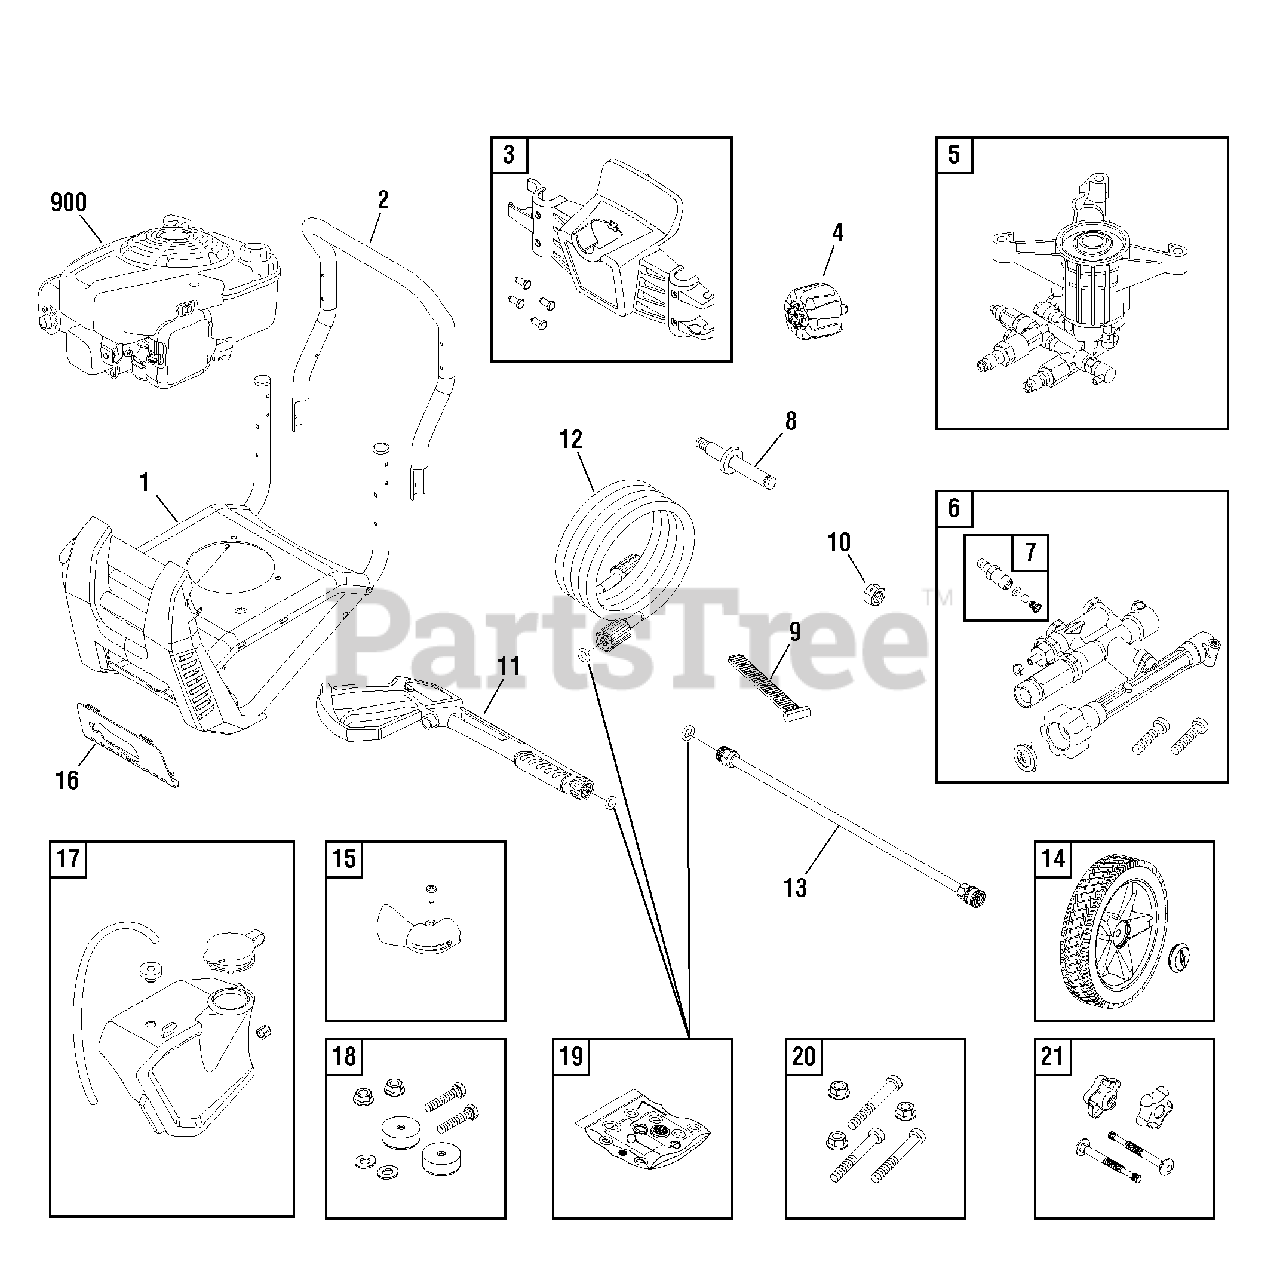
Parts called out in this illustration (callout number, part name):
5	PUMP
11	GUN
15	DEFLECTOR-EXHAUST
17	TANK-CHEMICAL
18	MOUNT-VIBRATION
20	KIT-HARDWARE PUMP MOUNTING
21	KIT-HARDWARE HANDLE
900	* ENGINE
